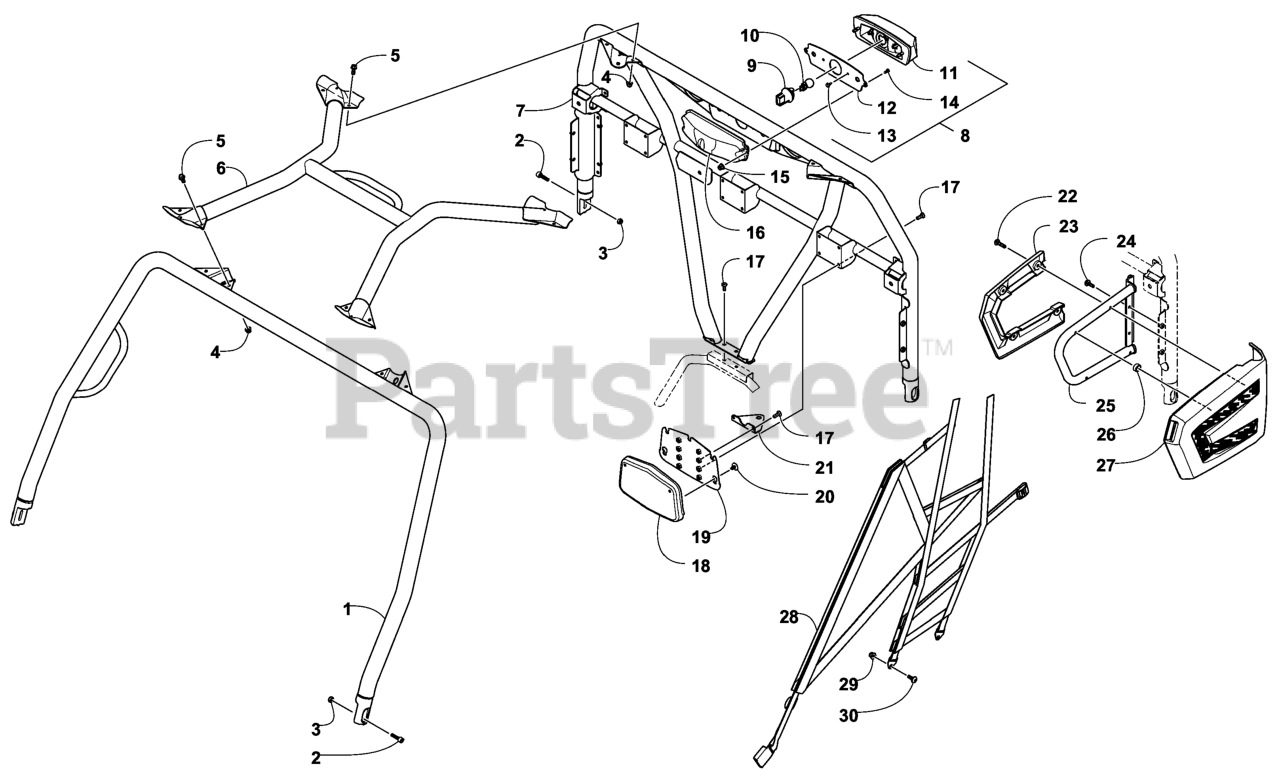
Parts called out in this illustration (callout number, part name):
1	HOOP-CANOPY, FRONT
2	SCREW-HSH
3	NUT-HH, LOCK
4	NUT-HHF, LOCK (NI)
5	SCREW-HFH
6	CANOPY-TOP
7	HOOP-CANOPY, REAR
8	TAIL LIGHT ASM
9	SOCKET-TAIL LIGHT
10	BULB-TAIL LIGHT
11	HOUSING-TAIL LIGHT
12	BRACKET-MOUNT, TAILLIGHT
13	SCREW-HWH, SELF TAP
14	SCREW-TSPNH
15	LINKAGE,LOWER CALIPER RH
16	COVER-TAILLIGHT
17	SCREW-TSPRH
18	PAD-HEADREST
19	MOUNT-HEADREST
21	BRACKET-MOUNT, FLAG
22	SCREW-TSPRH
23	GUARD-SHOULDER INNER, RH
24	GUARD-SHOULDER INNER, LH
24	SCREW-TSPRH
25	SUPPORT-SHOULDER GUARD, R
26	SUPPORT-SHOULDER GUARD, L
26	SLEEVE-METAL
27	GUARD-SHOULDER, RH
28	GUARD-SHOULDER, LH
28	GUARD-SHOULDER NET, RH
29	GUARD-SHOULDER NET, LH
29	NUT-HHF, LOCK (NI)
30	BOLT-SHOULDER
